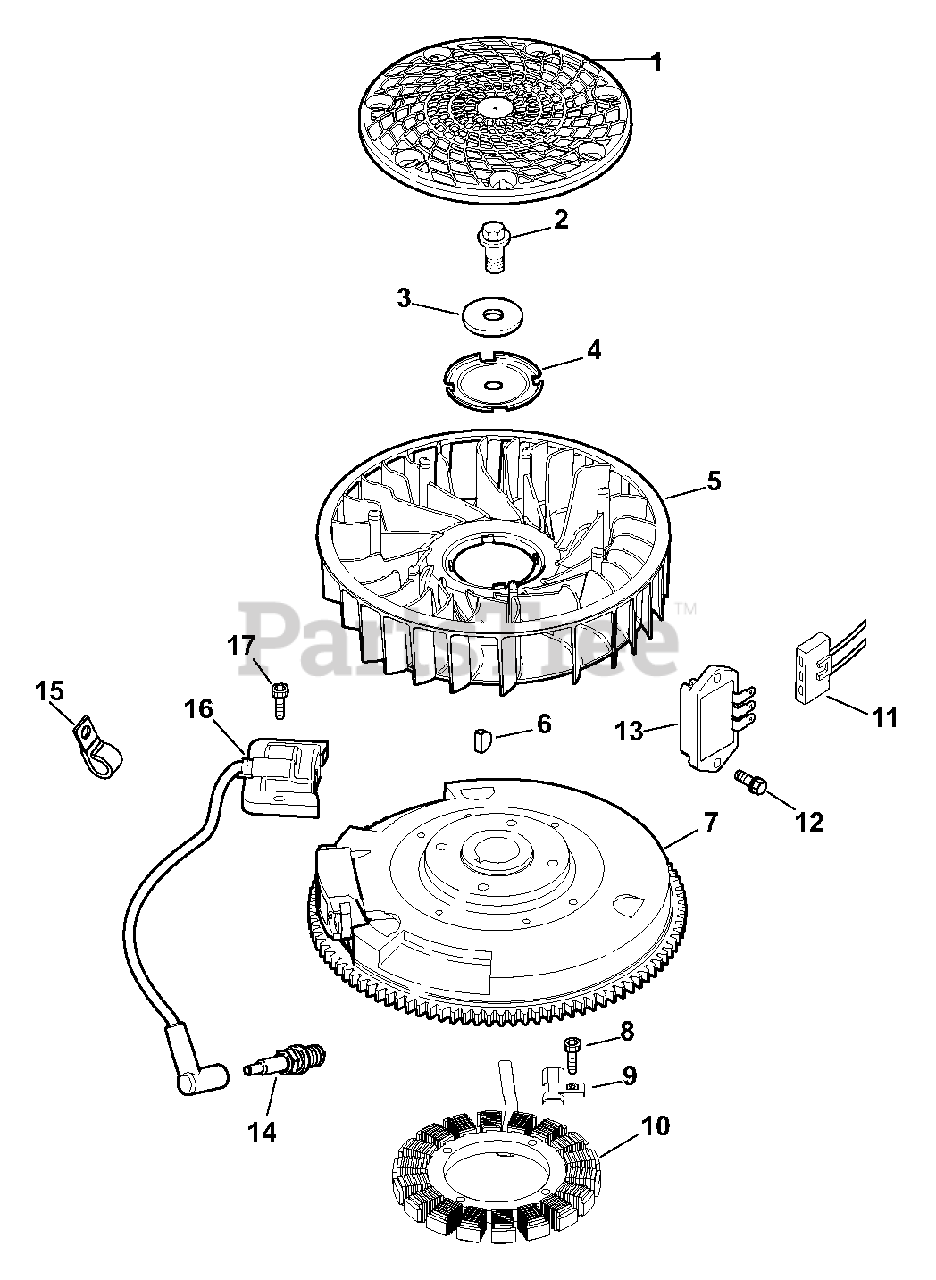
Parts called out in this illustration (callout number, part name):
1	Screen, Grass
2	Screw, Flg M1.0x1.5x45
3	Washer, Flat 13/32"
4	Plate, Fan Mounting
5	Fan
6	Key, 3/16" X 5/8"
7	Flywheel
8	Screw, Skt Thd Frm M5x0.8x25
9	Clip, Stator Wire
10	Kit, 15 Amp Stator
11	Connector (3 Contact)
12	Screw, Flg Thd Frm M5xo.8x20
13	Rectifier-regulator
14	Plug, Spark
15	Clip, Cable
16	Module, Ignition
17	Screw, Skt Thd Frm M5x0.8x25
